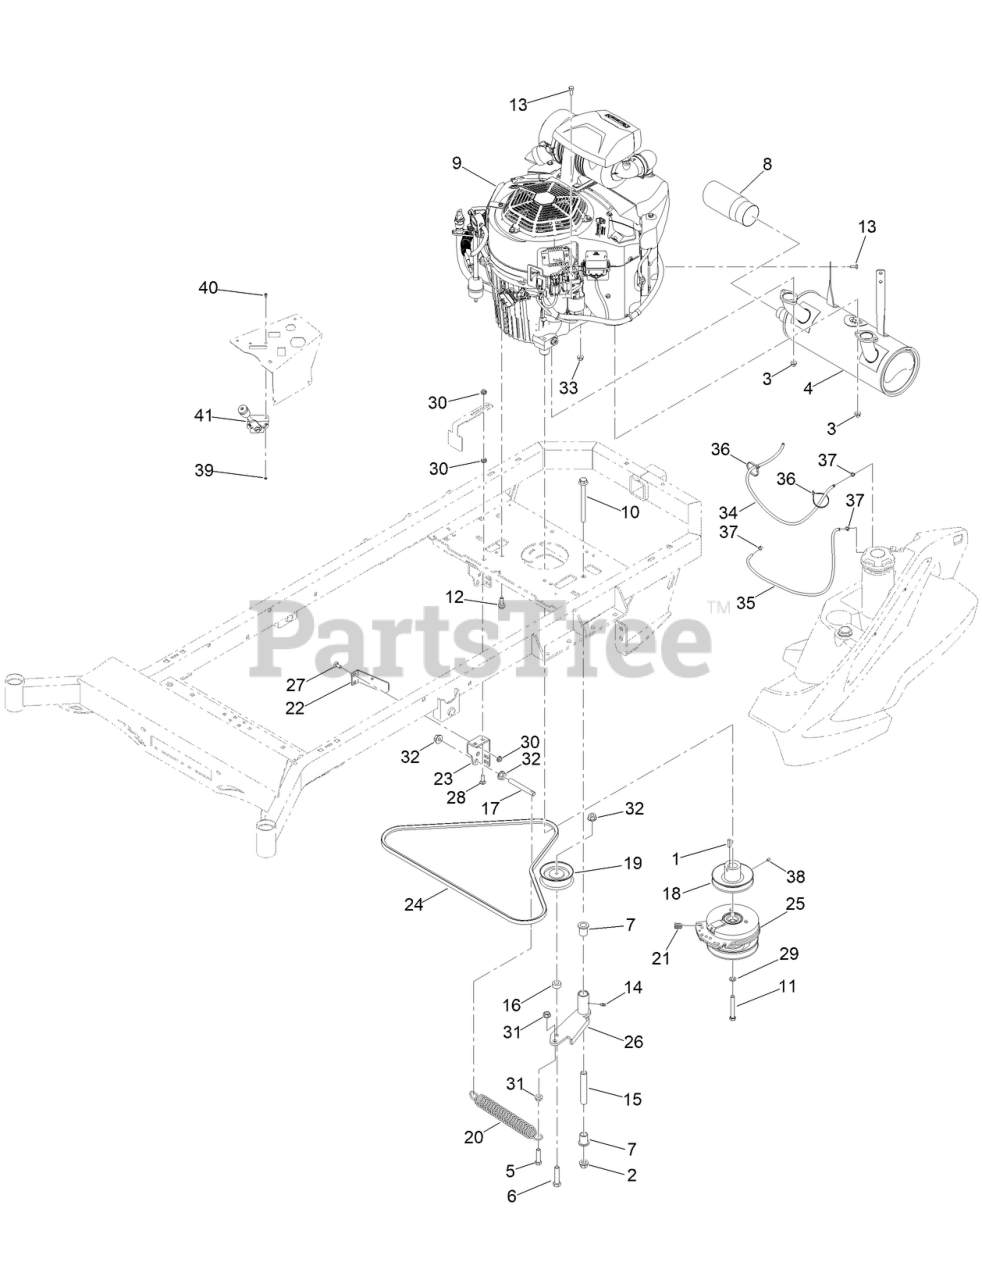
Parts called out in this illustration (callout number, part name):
2	NUT-LOCK
3	NUT-HF
4	MUFFLER W/ ARRESTER-6INOD-1.5INTP
5	SCREW-HH
6	SCREW-HH
7	3/4IN ID X15/16IN OD X 1-1/8IN FLNG BUSH
8	MWR CHROME EXHAUST TIP
9	KAWASAKI FXT1000V-EFI ENGN
10	1/2-13 X 5-1/2 HEX FLANGE BOLT GR 8 ZY
11	7/16-20 X 3 HEX C/S GR 8 ZC YELLOW
12	3/8-16 X 1-1/8 IND HWH W/SERR TRI LOB ZY
13	M8-1.25 X 20MM HEX FLANGE BOLT ZINC 10.9
14	1/4IN DRIVE TYPE GREASE FITTING YZ
15	MWR INNER IDLER SPACER
16	MWR PULLEY SPACER
17	MWR PUMP IDLER SPRING TENSIONER
18	MWR HYDRAULIC PUMP DRIVE PULLEY (B-BELT)
19	4IN DIESEL AND ECONOMY MWER IDLER PULLEY
20	MWR DECK SPRING
21	MWR CLUTCH ROTATION STOP BRKT SLEEVE
22	MWR CLUTCH ANTIROTATION BRKT BLACK
23	MWR PUMP IDLER TENSIONING BRKT BLACK
24	MWR PUMP BELT XD B X 69.40IN EFF LNGTH
25	WARNER PTO CLUTCH
26	4IN PUMP IDLER PULLEY ARM ASSY
27	BOLT-CARR
28	5/16-18 X 1-1/4 CARRIAGE BOLT ZC/YEL
29	WASHER-LOCK
31	NUT-HF
32	NUT-HHF
33	NUT-HF
34	MWR FUEL TANK BLACK 3/16IN VENT TUBE 1FT
35	1/4IN SAE J30R7 BULK HOSE 1FT
36	TIE-CABLE
37	1/2IN (#8) HOSE CLAMP
38	5/16-18 X 3/8 SOCKET SET SCREW
39	NUT-LOCK
40	10-24 X 1/2 SOCKET C/S 18-8 SS
41	KAWASAKI EFI THROTTLE
